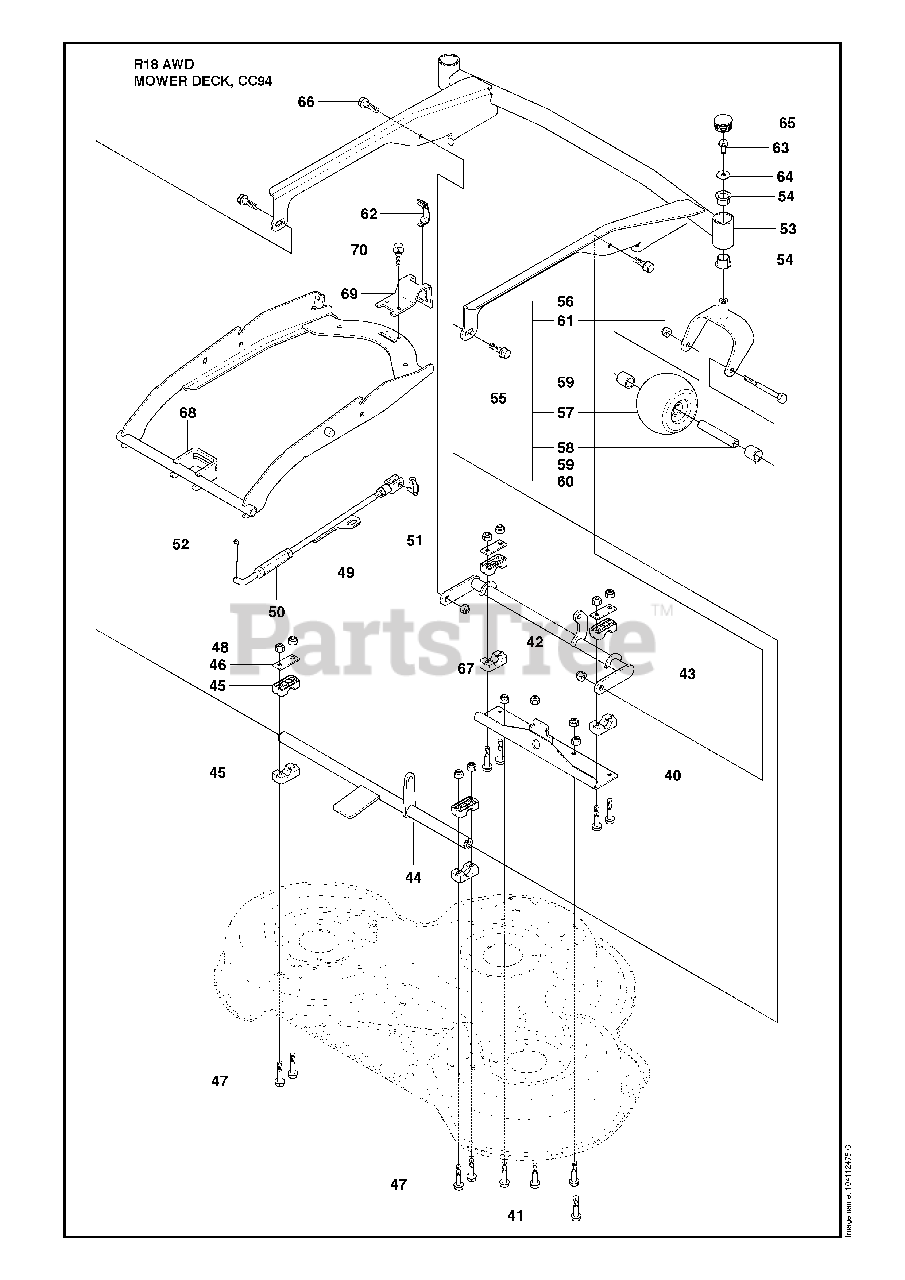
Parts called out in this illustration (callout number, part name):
1	CUTTING DECK WITH PLUG GREY
3	PLUG C93 & C94
5	SPINDLE ASSY
6	BEARING HOUSING
10	RP SPINDLE ASSY
11	BEARING HOUSING
14	BALL BEARING
16	WASHER BRB 8.4X17
17	LOCKNUT M8
24	BLADE
25	WASHER
27	BELT TENSIONER ASSY
28	BELT TENSIONING ARM
32	WASHER
34	LOCKNUT M8
37	BELT COVER C93 & C94 GREY
42	LOCKNUT M8
48	LOCKNUT M8
49	PARALLELL ROD ASSY
50	PARALLEL ROD
51	RETAINER
53	DECK FRAME
55	PIVOT WHEEL ASSY
57	DECK ROLLER, FRONT
61	NUT
62	CLIP GRAY
66	Screw
67	LOCKNUT M8
68	DECK ATTACHMENT
70	Screw
